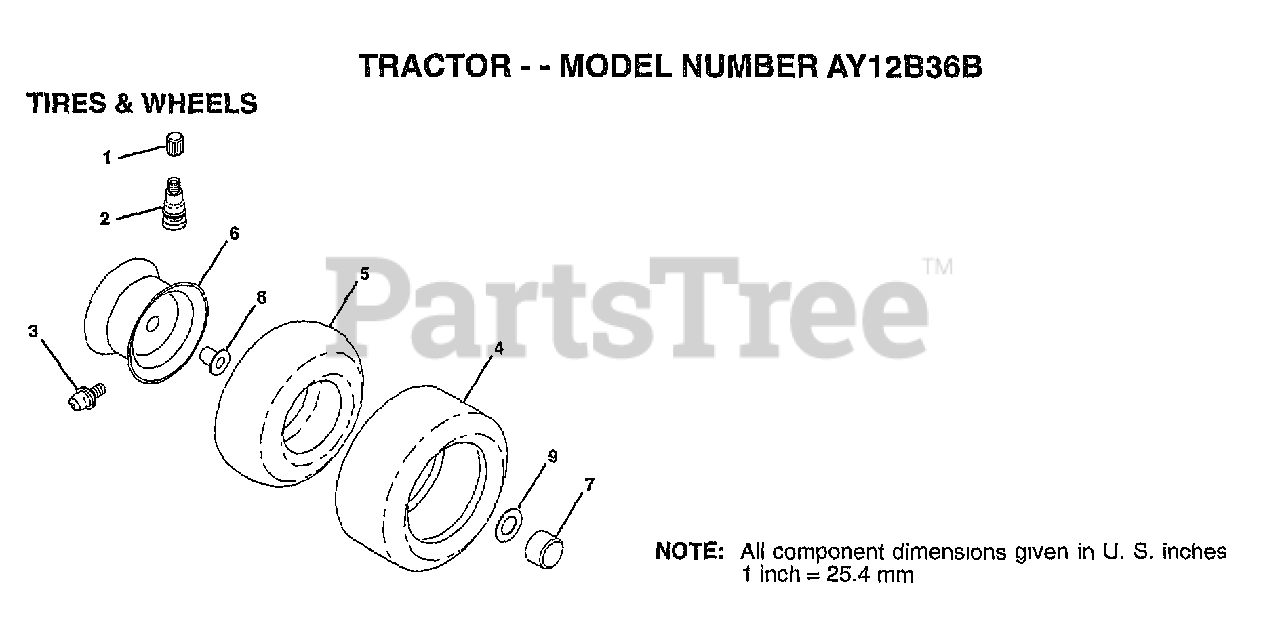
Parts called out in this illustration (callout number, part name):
1	VALVE CAP
2	VALVE STEM LT
3	FITTING LT
5	TUBE.5.3/4.5/6
5	TUBE.16X6.5/7.5-8
6	"RIM 6"" FRONT 421"
6	"RIM REAR 8"""
7	HUB CAP
8	"FLANGE, BEARING"
9	WASHER
